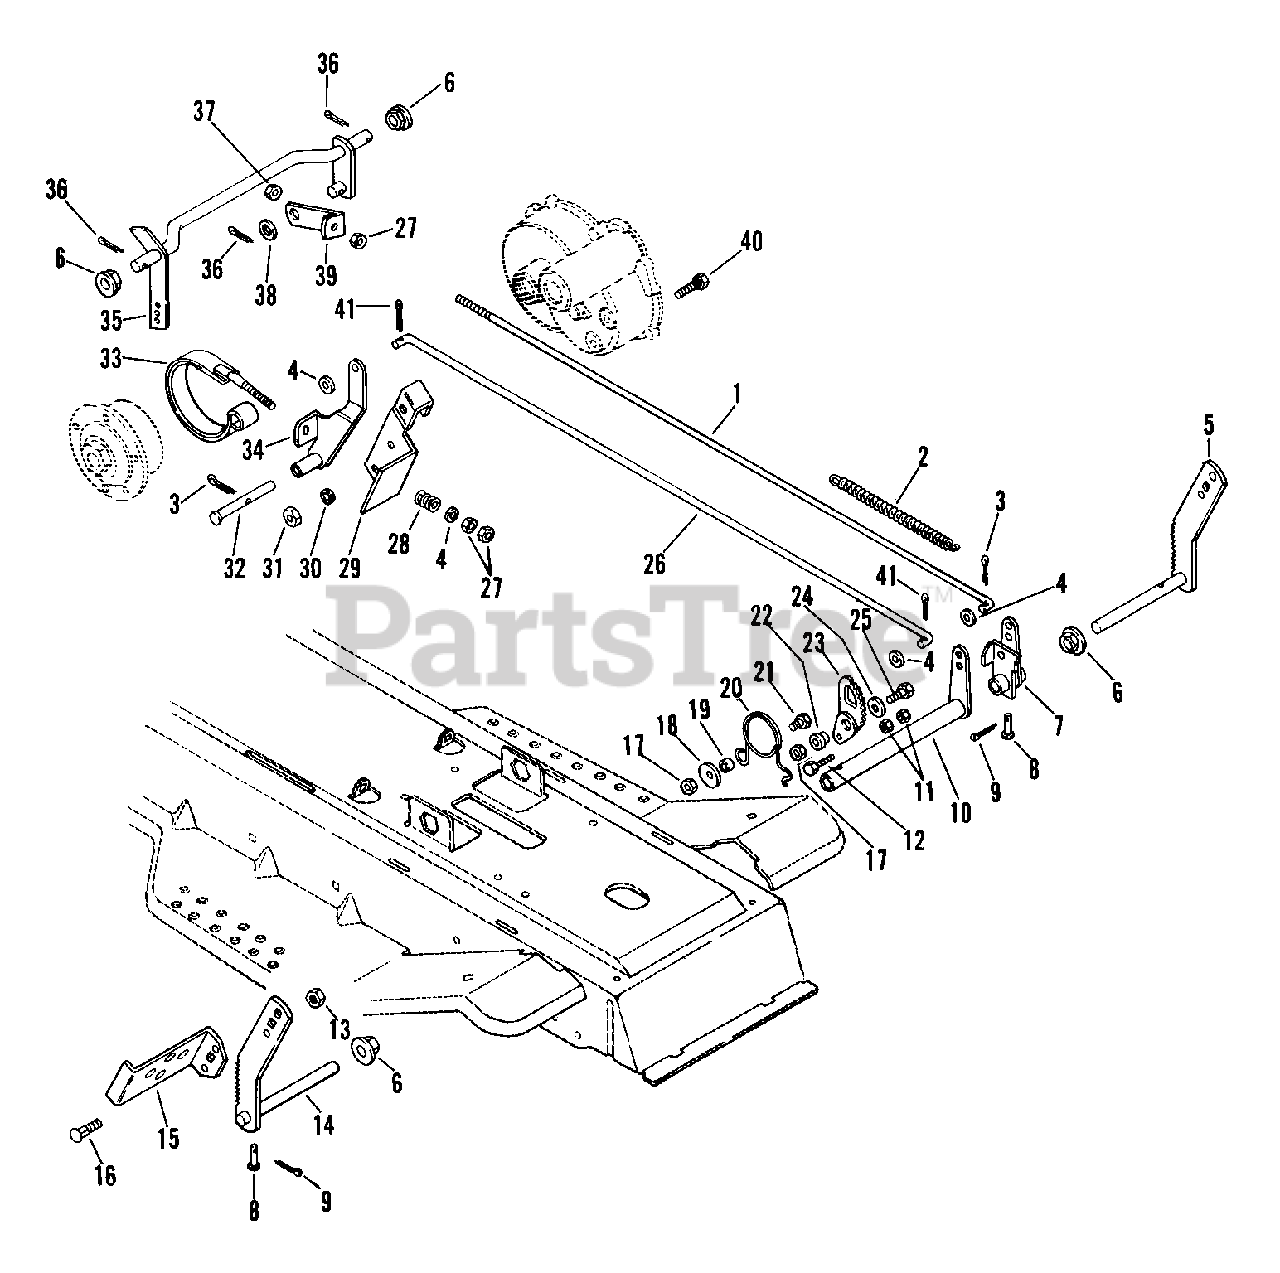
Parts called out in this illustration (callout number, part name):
1	ROD, CLUTCH
2	SG-TENS 2.25 FREE LENGTH
3	PIN-COTR .12X.75 PL
4	WSHR-FL-STL .323X.625X.062 PL
5	CLUTCH PEDAL ARM
6	FLANGE BUSHING
7	CLUTCH ARM
8	PIN-CLEV .185X1.00 SP
9	PIN-COTR .06X.50
10	BRAKE ARM
11	NUT 8-32 PL
12	SCR-MCH 8-32X1.00 SLTR PL
13	NUT-LK-JAM-CTR .375-16 PL
14	BRAKE PEDAL ARM
16	BLT-RDHDSQNK .38-16X.75 SHT PL
17	NUT-LK .312-18 GR A PL
18	WSHR-FL-STL .344X1.125X.063PL
19	SPACER BUSHING .5 X .32 X .163
20	SG-TORS .125X1.0X1.75
21	BLT-HEX .31-18X.63 PL GR 2
22	SPACER -SHLD .344X.500X.469
23	BRAKE LATCH
24	WSHR-FL-STL .38X.875X.083 PL
25	BLT-HEX .31-18X1.00 PL GR 2
26	BRAKE ROD
27	NUT-HEX .312-18
28	SG-COMP .105X.585X.75
29	BRAKE BRACKET
30	WSHR-LK-INT .313X.030 PL
31	NUT-HEAVY .312-18 PL
32	PIN-CLEV .371X3.25
33	BRAKE BAND
34	BRAKE LEVER
35	CLUTCH SHAFT
36	PIN-COTR .12X1.0 PL
37	NUT-LK-NYL.312-18 PL
38	WSHR-FL-STL .520X.810X.033
39	CLUTCH BRACKET
40	BLT-SERRDHD SL .31-18X.75 YZ
41	PIN-COTR .09X.75 PL
